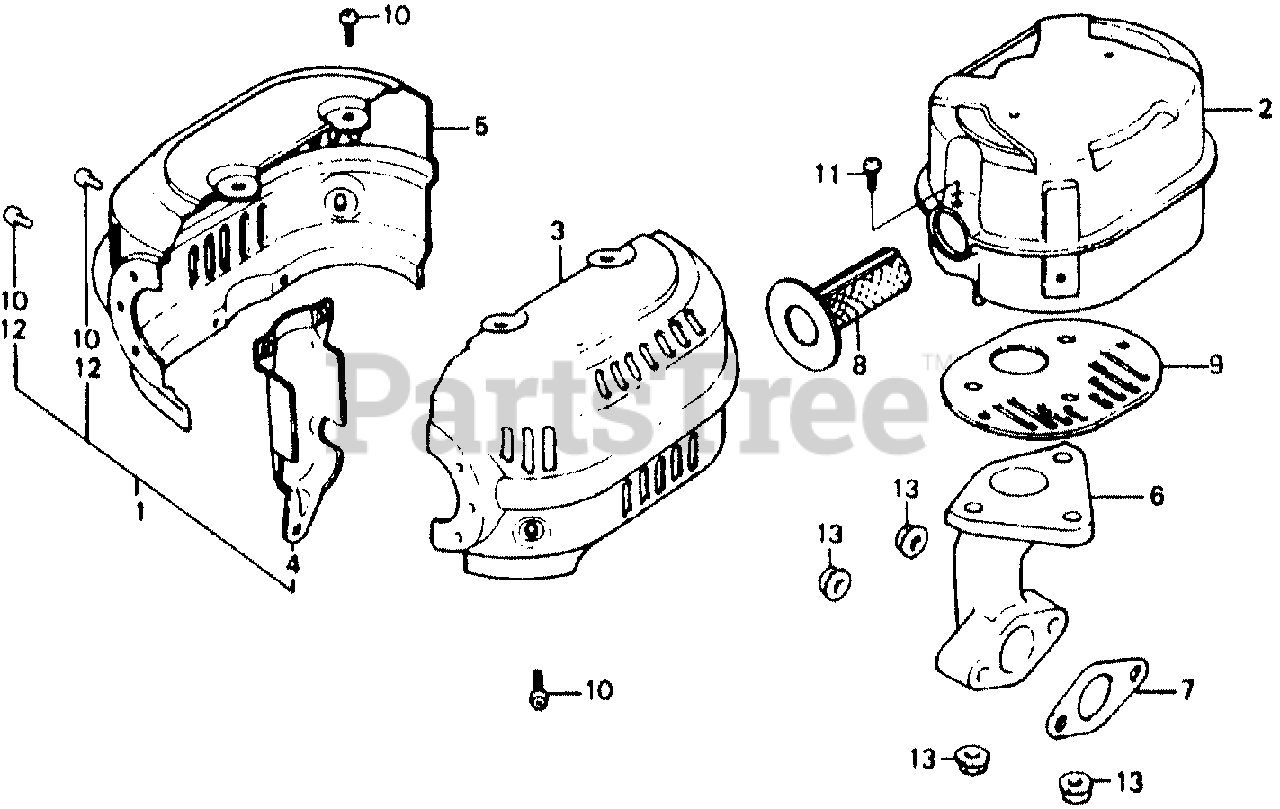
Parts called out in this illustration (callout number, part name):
1	PROTECTOR, EX. PIPE
3	PROTECTOR, R. MUFFLER (ALUMINIZED)
4	PROTECTOR, EX. PIPE
5	PROTECTOR, L. MUFFLER (ALUMINIZED)
7	GASKET, EX. PIPE
7	GASKET, EX. PIPE (WACKER)
8	ARRESTER, SPARK
9	GASKET, MUFFLER
10	SCREW, TAPPING (5X8)
11	SCREW, TAPPING (4X6)
12	SCREW, PAN (5X8)
13	NUT, FLANGE (8MM)
